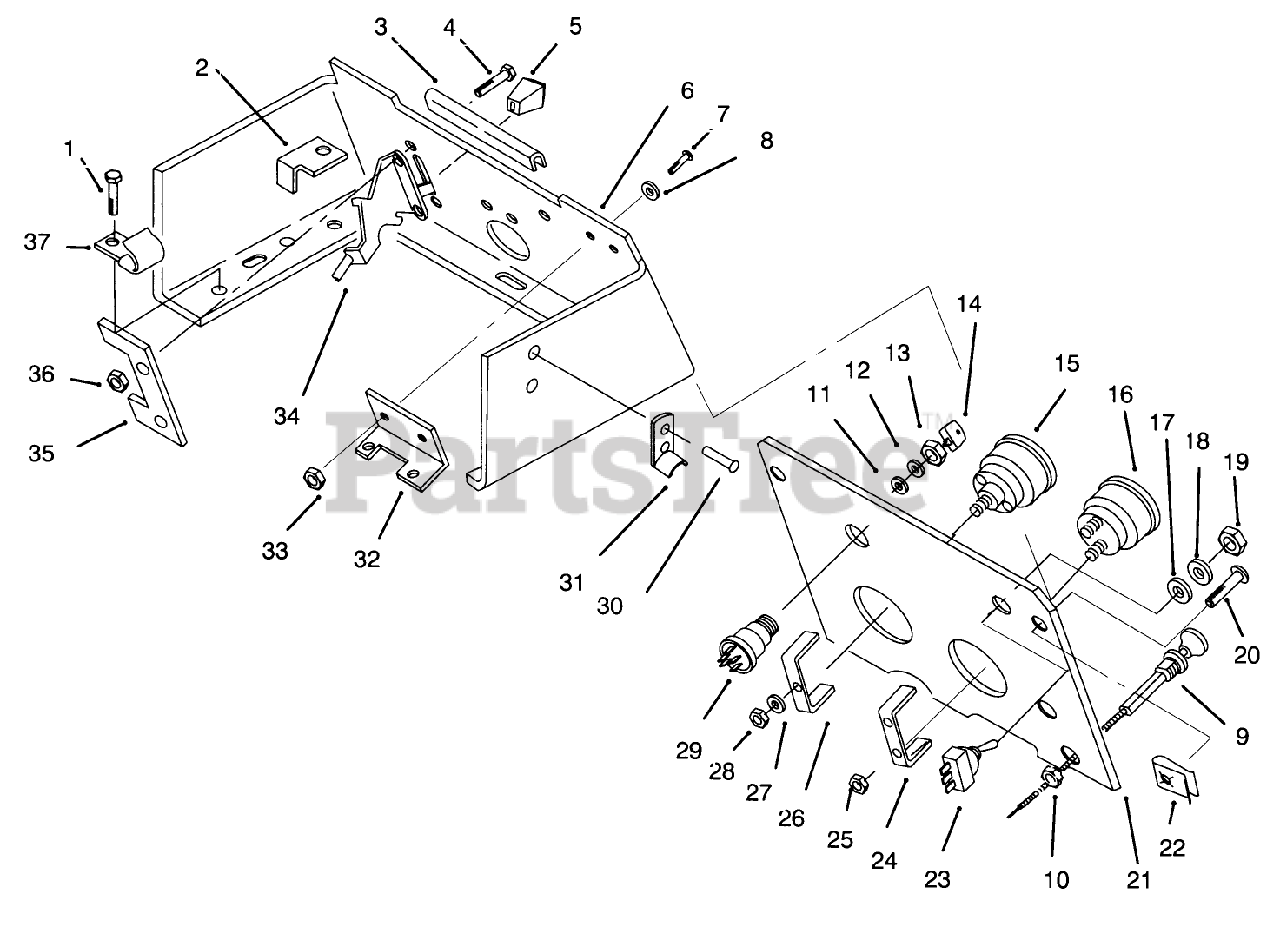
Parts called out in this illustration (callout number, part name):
1	SCREW
2	STOP-PTO
3	EDGING-CONSOLE
6	CONSOLE *B
7	SCREW
9	CONTROL CHOKE
10	NUT-HEX PALNUT
14	KEY-IGNITION
16	VOLTMETER
17	Washer
18	TAB-WASHER
19	*DISC**
22	CLIP
23	SWITCH-LIGHTS
24	CLAMP-MOUNTING
25	HEX NUT 10-32 E.S. + + USE 3296-21 + +
26	CLAMP-HOUR METER
28	NUT-HEX
29	KEY SWITCH ASM
31	KEEPER-LATCH
32	BRACKET
34	CONTROL-THROTTLE
35	Washer
37	J-CLIP
